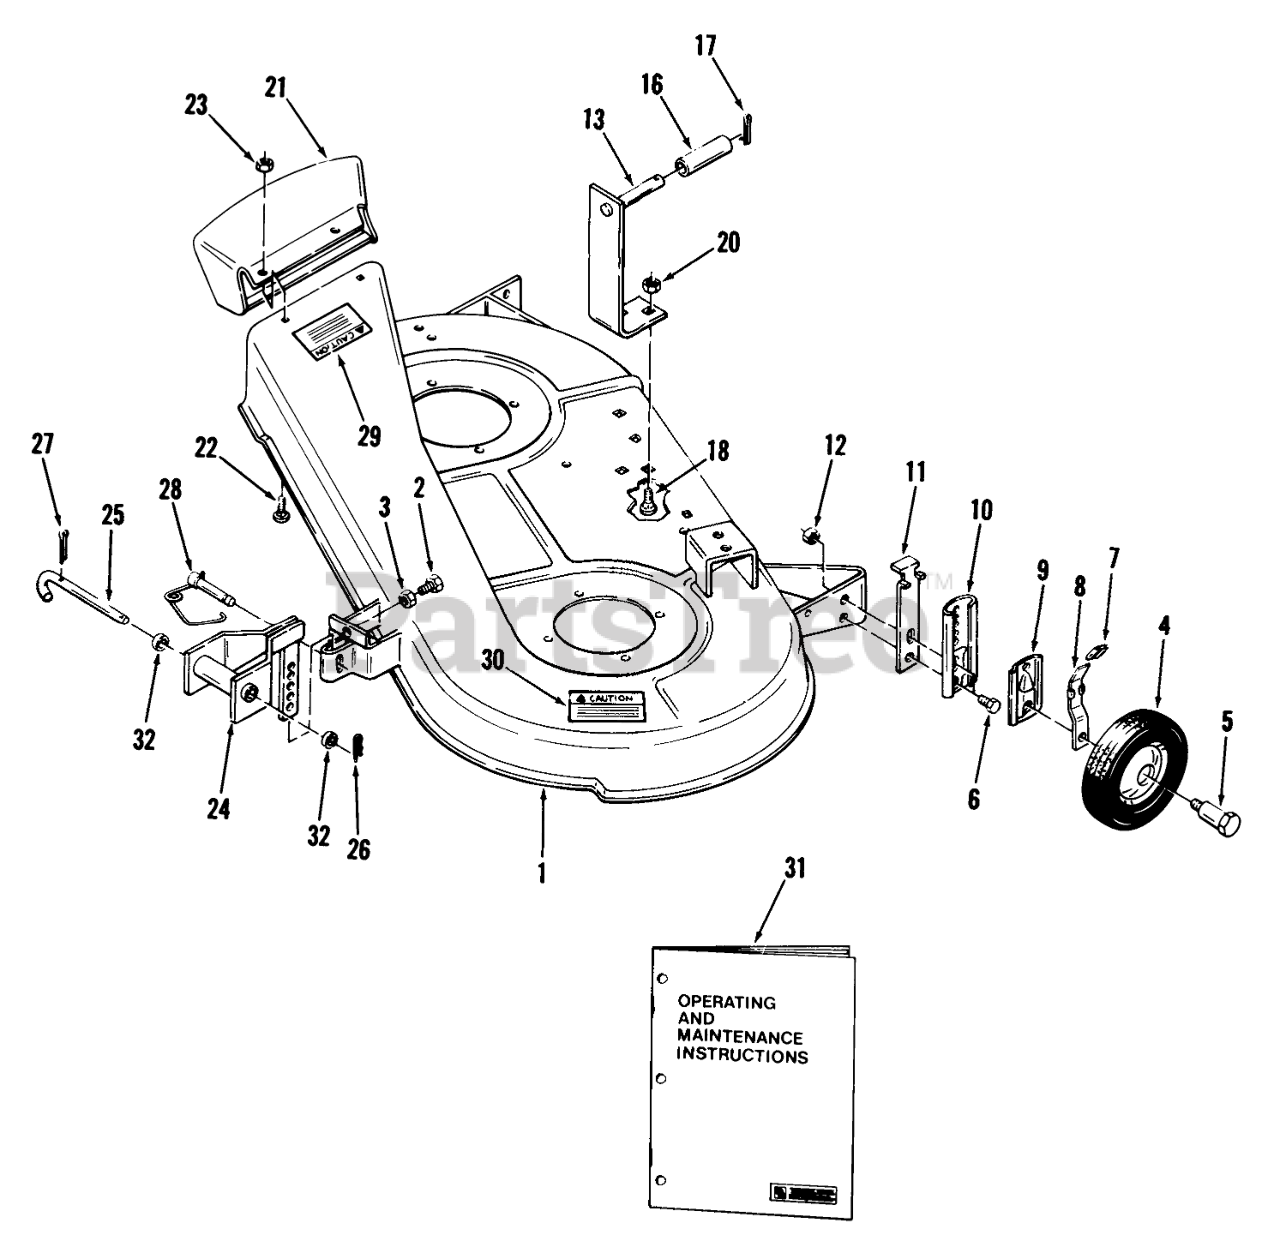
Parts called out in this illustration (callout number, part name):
1	Mower Deck
2	BOLT
3	Nut
4	Wheel 6 X 1.25
5	BOLT-SHOULDER
6	Bolt-Special
7	HT ADJ TIP RED VINYL
8	HT ADJ SPRING LEVER
9	HT ADJ SLIDE
10	HT ADJ BACK PLATE
11	SAFETY-STOP& LIFT
12	Nut
13	Guide Bracket
16	SPACER
18	Bolt
20	Nut
21	ASSY-CHUTE EXT R
22	CARRIAGE BOLT -4
23	Nut
24	Front Hanger
25	"J" Pin
26	Hairpin Cotter
28	PIN-LOCKING
29	DECAL
30	Caution Decal
31	Operating and Maintenance Instructions
32	Washer
